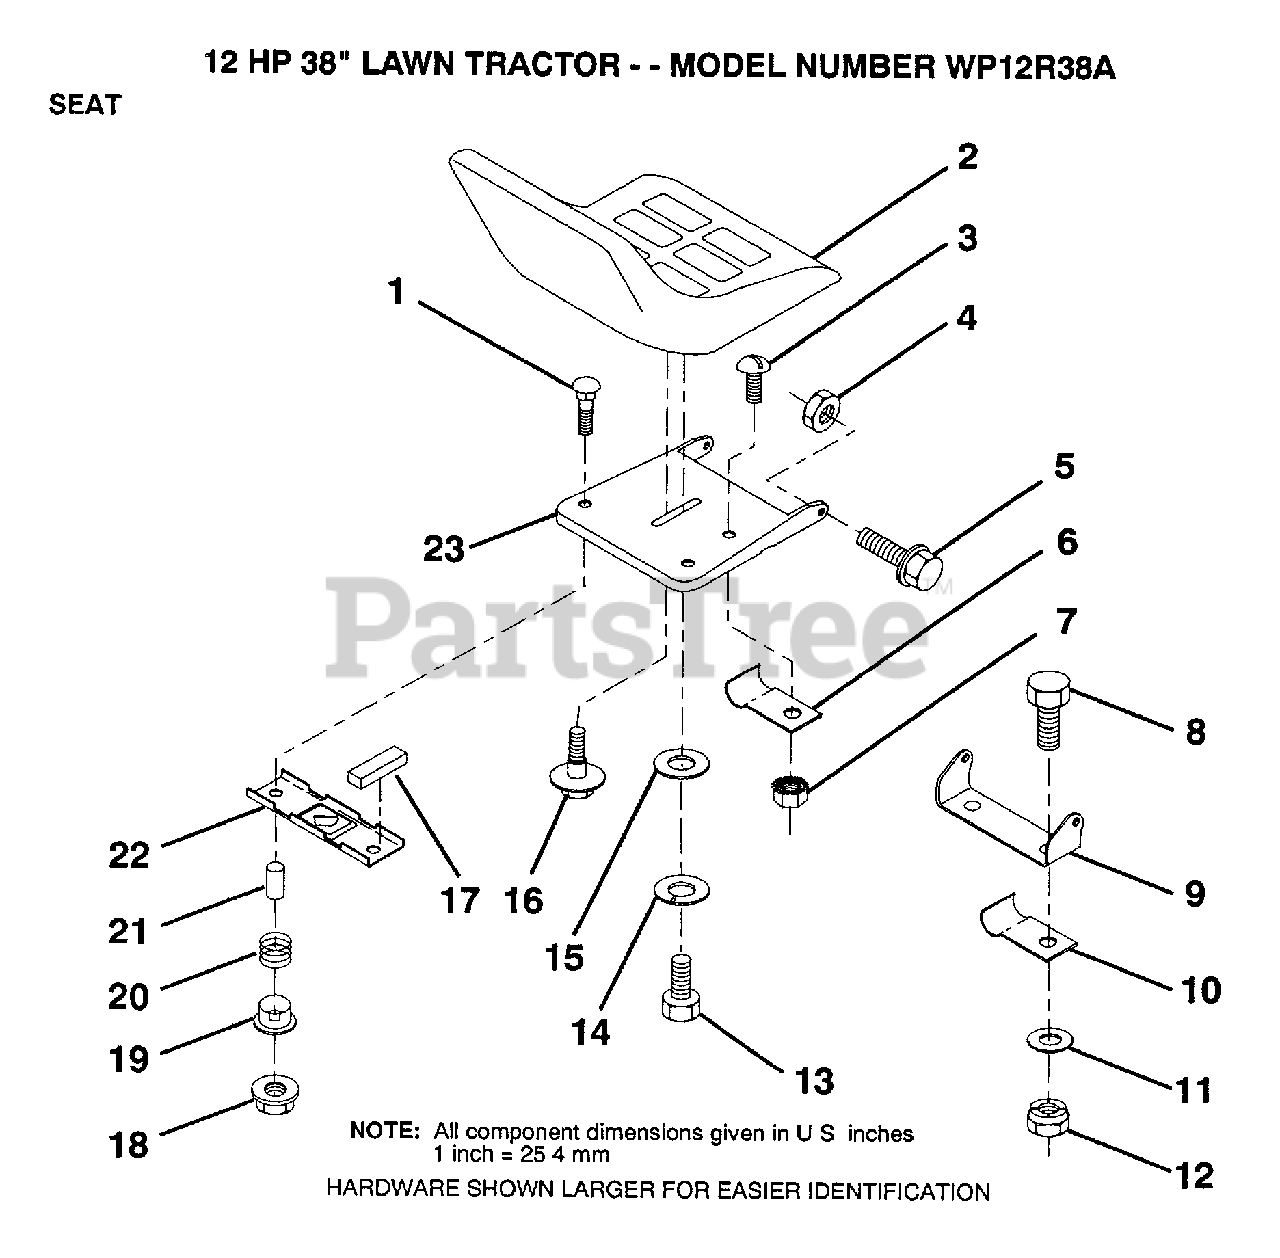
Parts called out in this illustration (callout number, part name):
7	"NUT,KEPS"
10	"CLIP,INSULATOR"
11	WASHER
13	BOLT
14	LOCKWASHER
15	WASHER
16	"BOLT,SHOULDER"
17	STRIP FORM
19	BUSHING
20	SPRING
21	SPACER SPLIT
22	BRKT SWITCH
